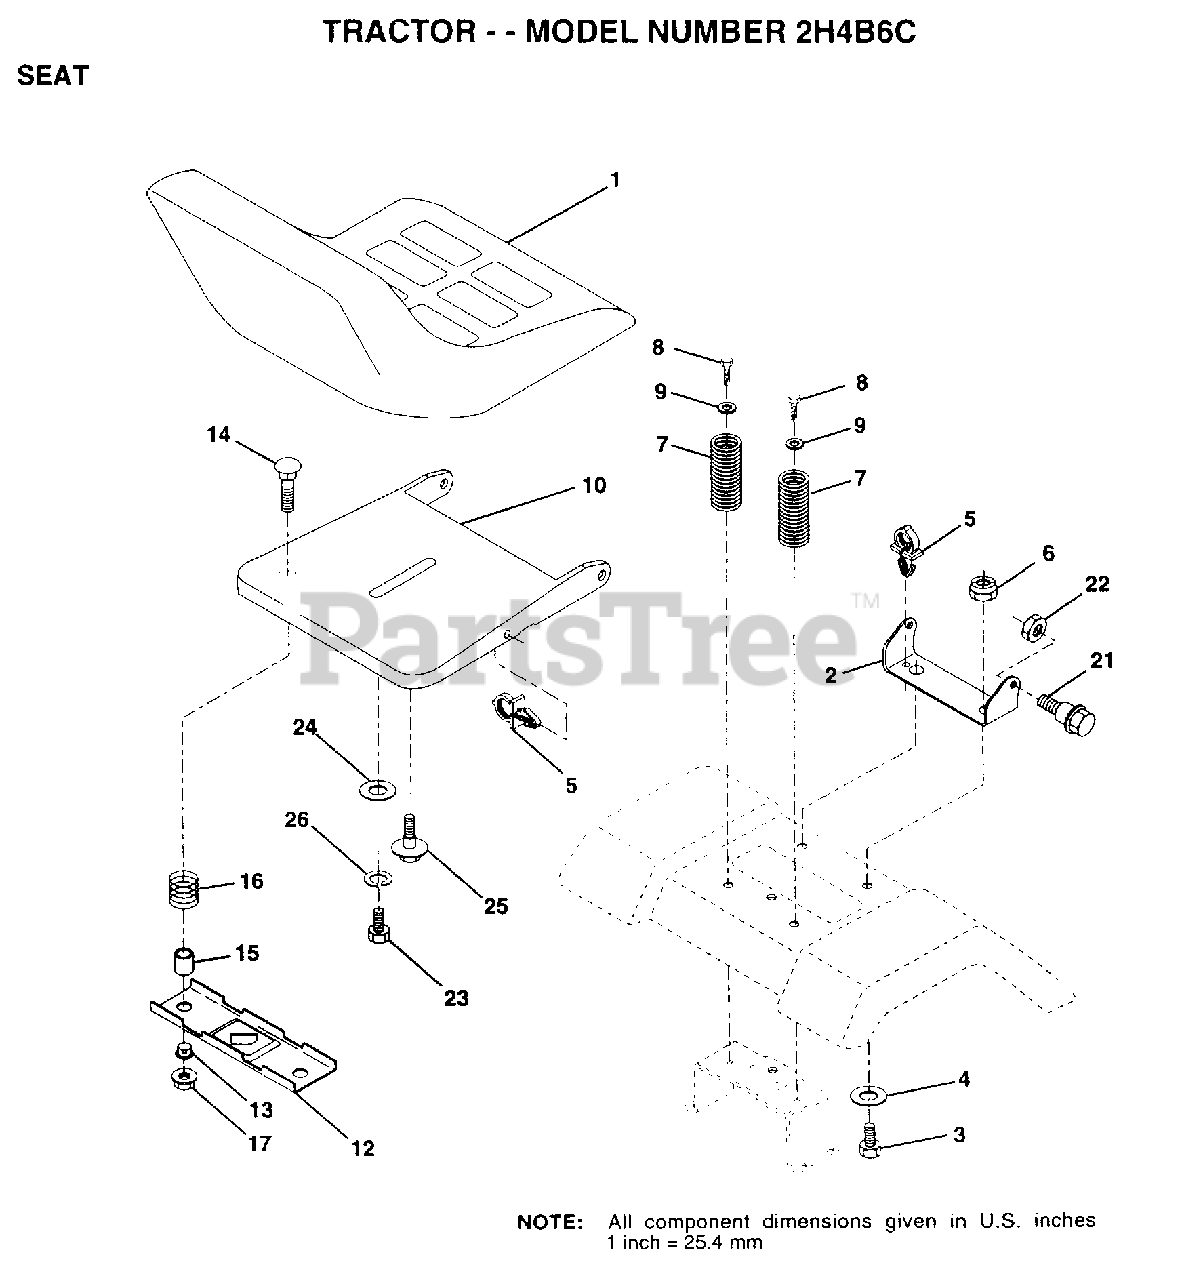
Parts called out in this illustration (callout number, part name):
2	BRACKET PVT SEAT
3	BOLT
4	WASHER PM
5	CLIP.PUSH-IN.HING
6	NUT
7	SPRING COMPRESSIO
8	SCREW GTV
9	WASHER
12	BRKT SWITCH
13	BUSHING
15	SPLIT SPACER
16	SPRING
21	"BOLT,SHOULDER"
22	NUT
23	BOLT
24	WASHER
25	"BOLT,SHOULDER"
26	LOCKWASHER
